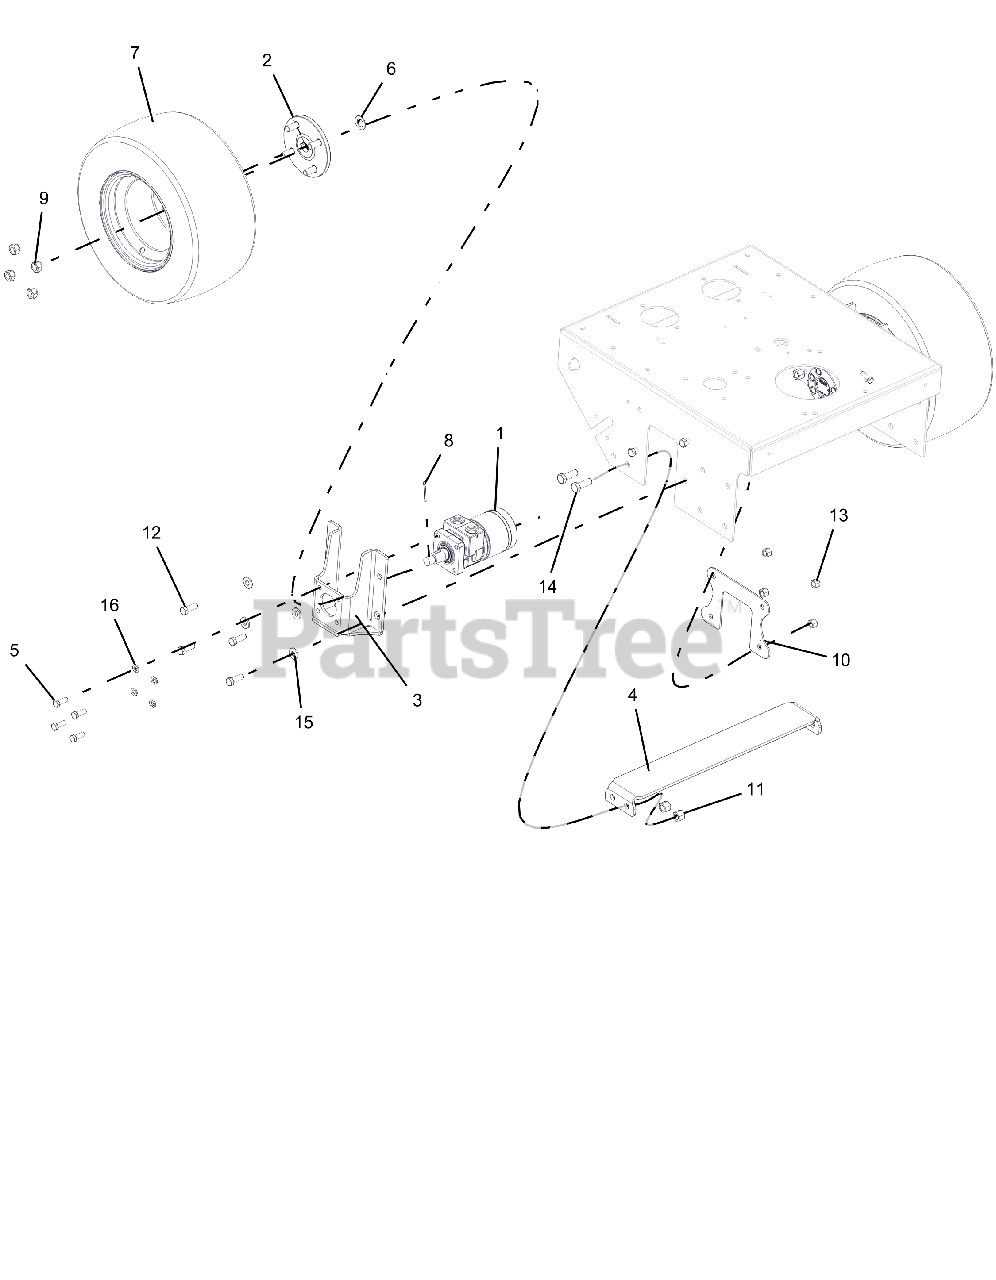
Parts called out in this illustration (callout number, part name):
1	MOTOR, HYDRAULIC WHEEL
2	ASSY, WHEEL HUB
3	WLDMT, WHEEL MOTOR BRACKET-RED
4	PLATE, ENGINE BED REAR 52/48-RED
5	BOLT, 3/8-16 X 1 GR8 BLACK
6	BUSHING, MACH .75 X 1.25 X .048
7	ASSM, WHL/TIRE 16X7.50-8 K500
8	PIN, COTTER
9	NUT, 1/2-20 LUG C
10	PLATE, ENGINE BED DOUBLE-RED
11	NUT-LK-NYL .50-13 YWZC
12	BLT-HEX .44-14X
13	NUT-LK-NYL .44-14 YWZC
14	BLT-HEX .50-13X1.50 GR5 YWZC
15	WSHR-FL-STL .468X1.00X.125 YWZC
16	WSHR-LK .38X.094 REG YWZC
